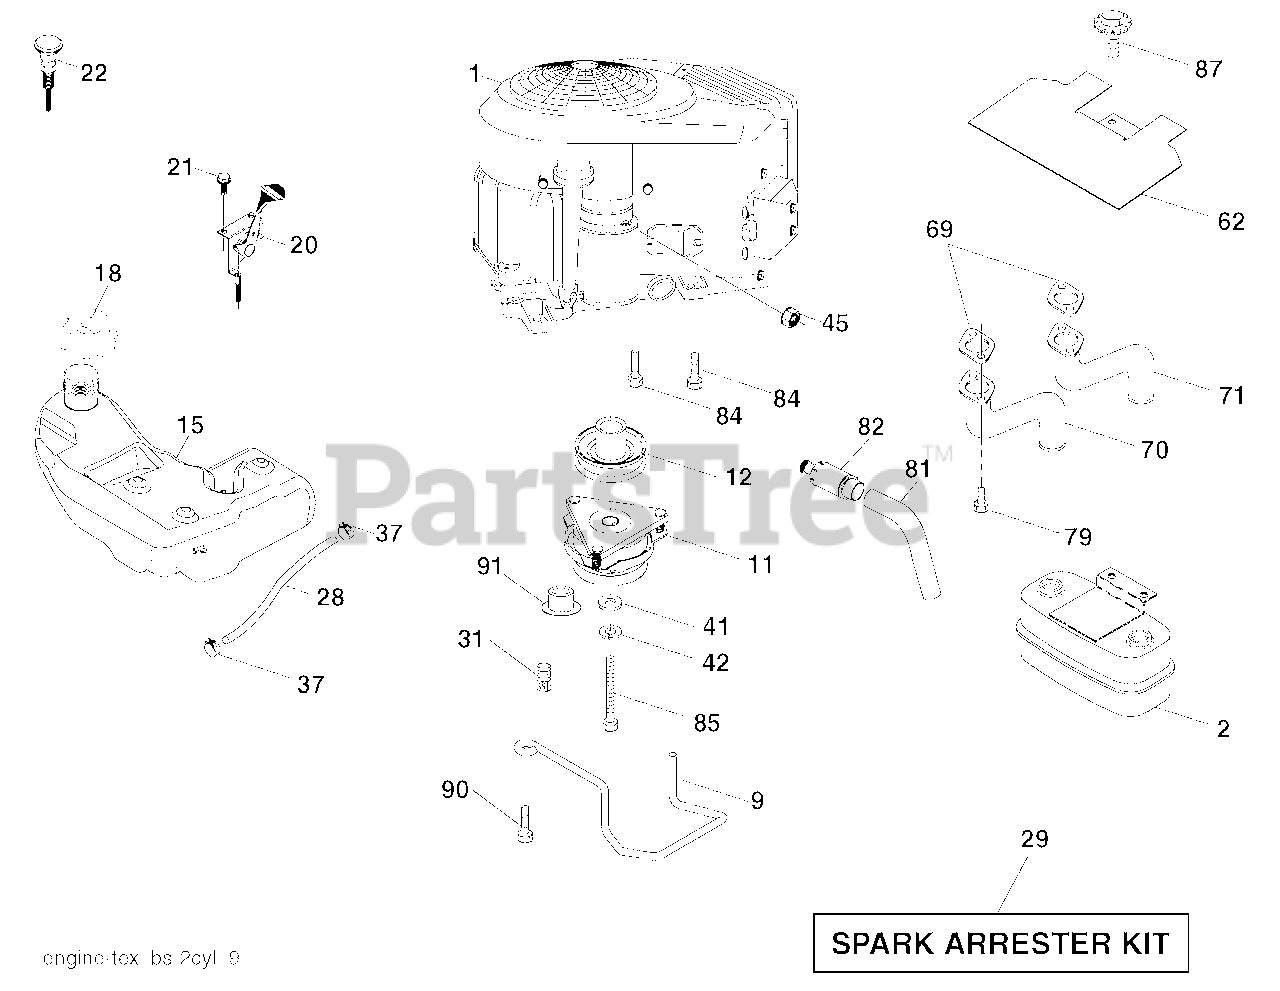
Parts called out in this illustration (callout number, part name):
2	Muffler
9	Keeper Belt Engine
11	Clutch Electric
12	Pulley Engine
15	Tank Fuel
18	Cap Asm.
20	Control Throttle
21	Screw #10 x 0.750 BOS Thread
22	Control Choke
28	Fuel Line
29	Spark Arrester Kit
31	Clip Push-In Hinged
37	Clamp Hose
41	Washer 1-1/2 OD x 15/32 ID x .250
42	Washer Lock 7/16
45	Nut Keps Hex 1/4-20 unc
62	Shield Heat Muffler
69	Gasket
70	Exhaust Tube LH
71	Exhaust Tube RH
79	Screw Socket Head 5/16-18 x 1
81	Tube Drain Oil Easy
82	Plug Drain Oil
84	Screw 3/8-16 x 1-1/4
85	Bolt Hex 7/16-20 x 3.75 Gr. 5
87	Bolt 5/16-18 x 1
90	Screw 3/8-16 x 1
91	Bushing 1.375 OD
